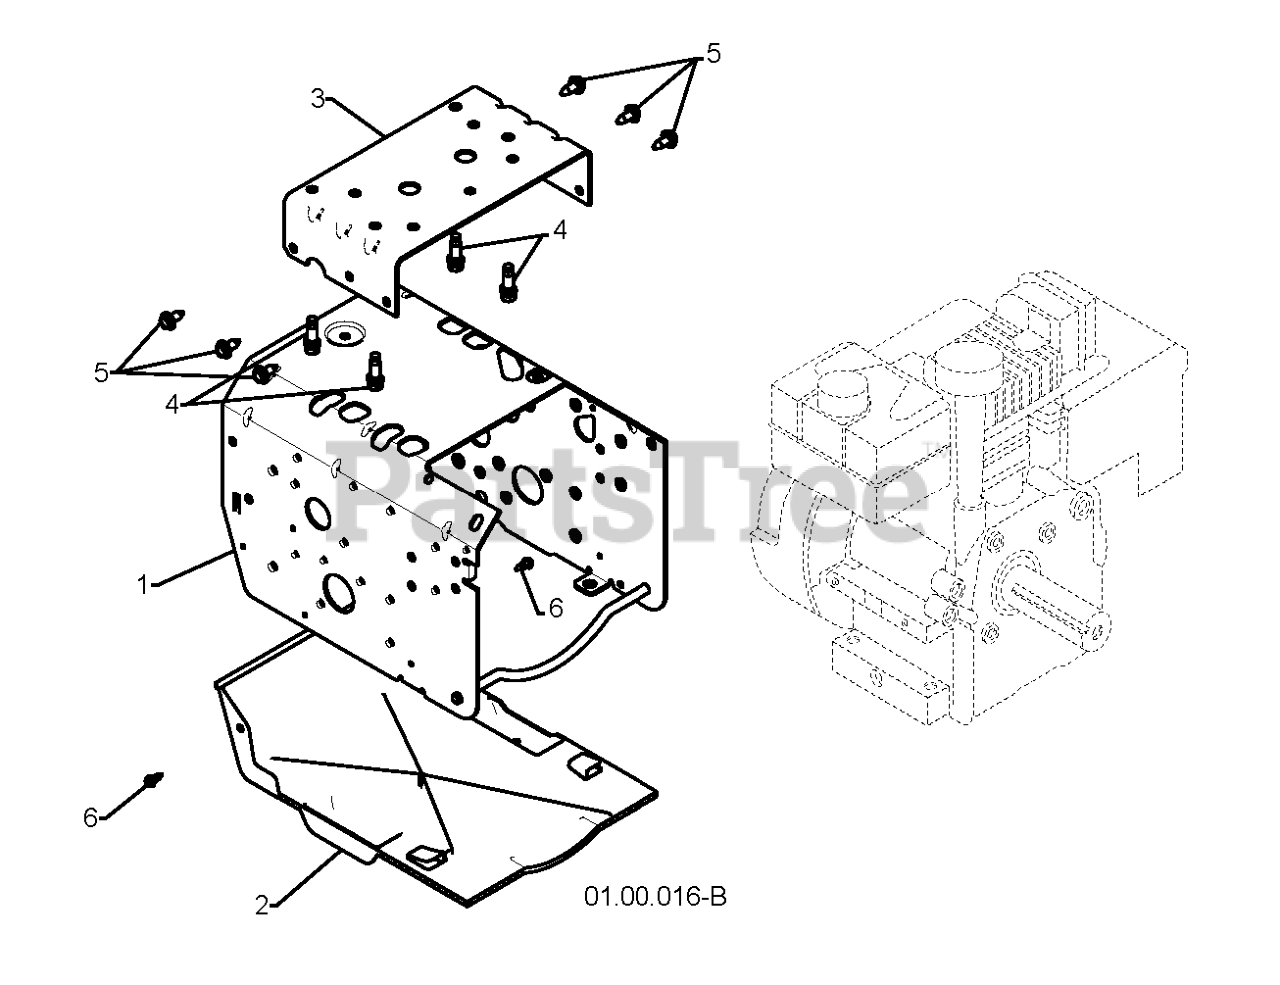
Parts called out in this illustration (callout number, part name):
1	FRAME.WELD.PNT.003BGP
2	PAN.BOTTOM.PLASTIC
3	PLATE.ENGINE.MOUNT.ORANGE
4	BOLT 3/8-16X1-1/8
5	BOLT.HEX.HD.WASHER.5/16-18X.75
6	SCREW, HEX HEAD, TAPPING
